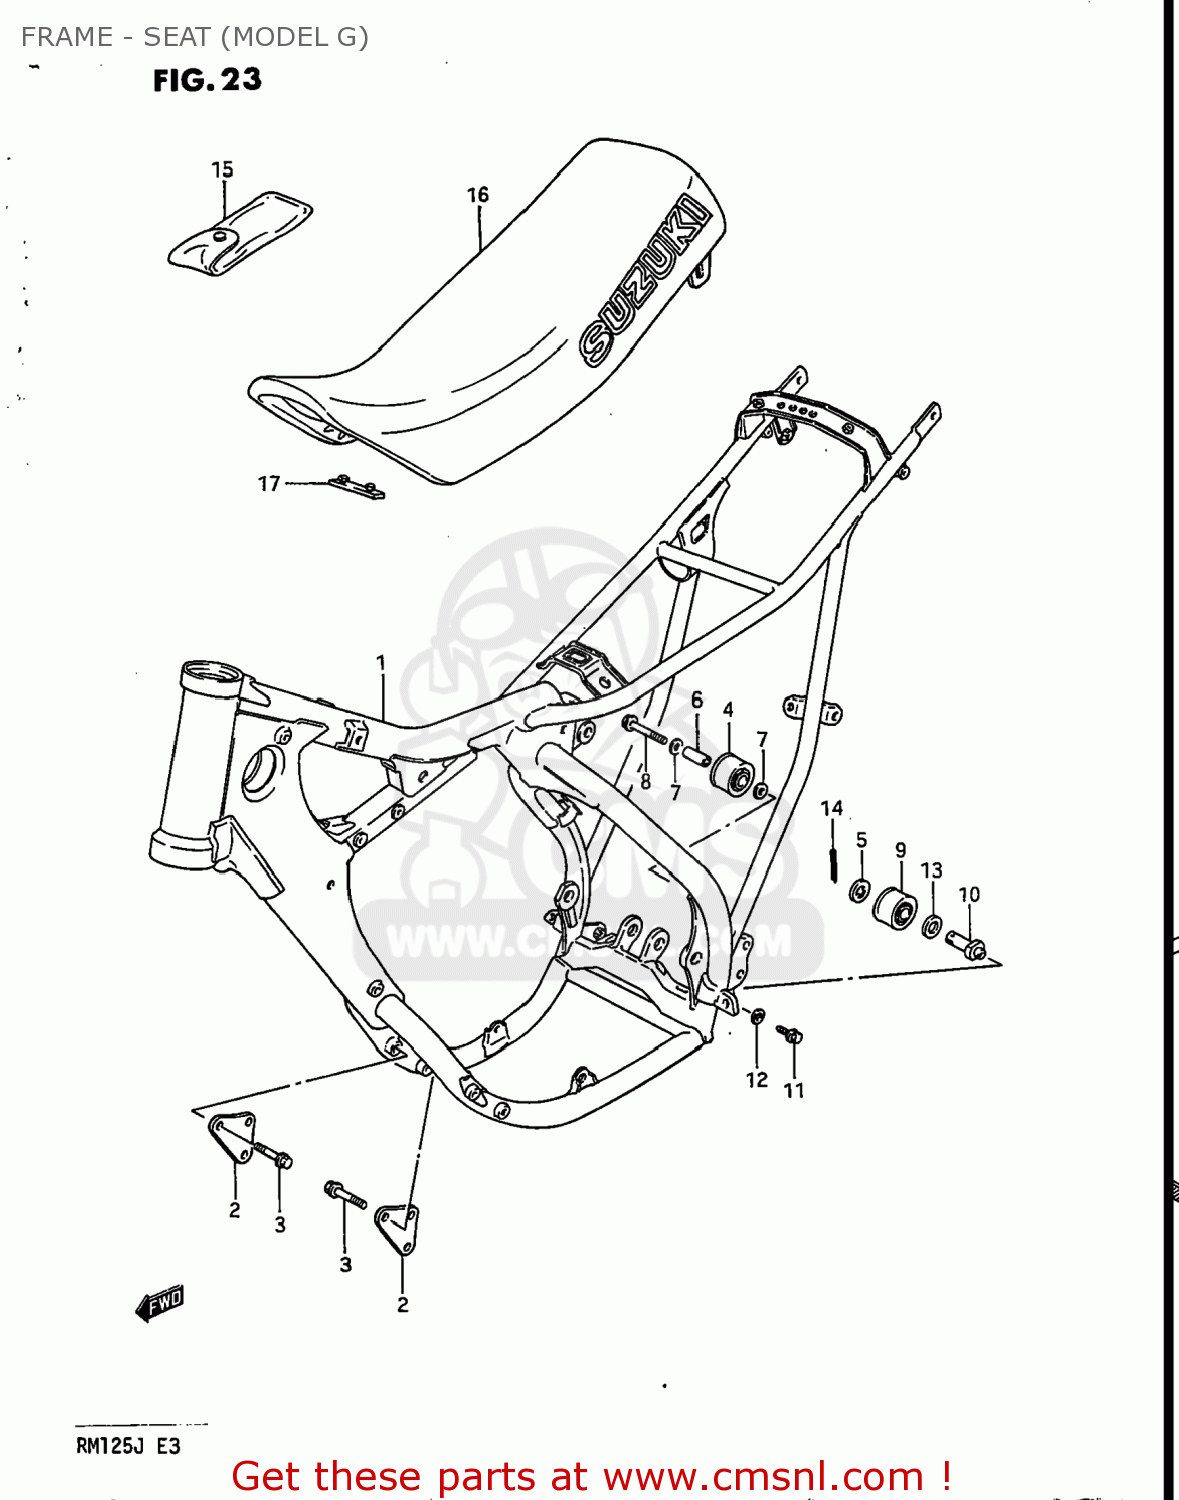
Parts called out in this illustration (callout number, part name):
1	FRAME
2	PLATE,ENGINE MOUNTING
3	BOLT(8X36)
4	ROLLER,CHAIN CONTROL
5	WASHER
6	SPACER(8.6X12X25.5)
7	WASHER
8	BOLT(8X45)
9	ROLLER,CHAIN CONTROL
10	BOSS,CHAIN LENGTH ROLLER
11	BOLT 6X16
12	WASHER
13	WASHER
14	PIN 25X20
15	TOOL SET
16	SEAT ASSEMBLY
17	CUSHION
